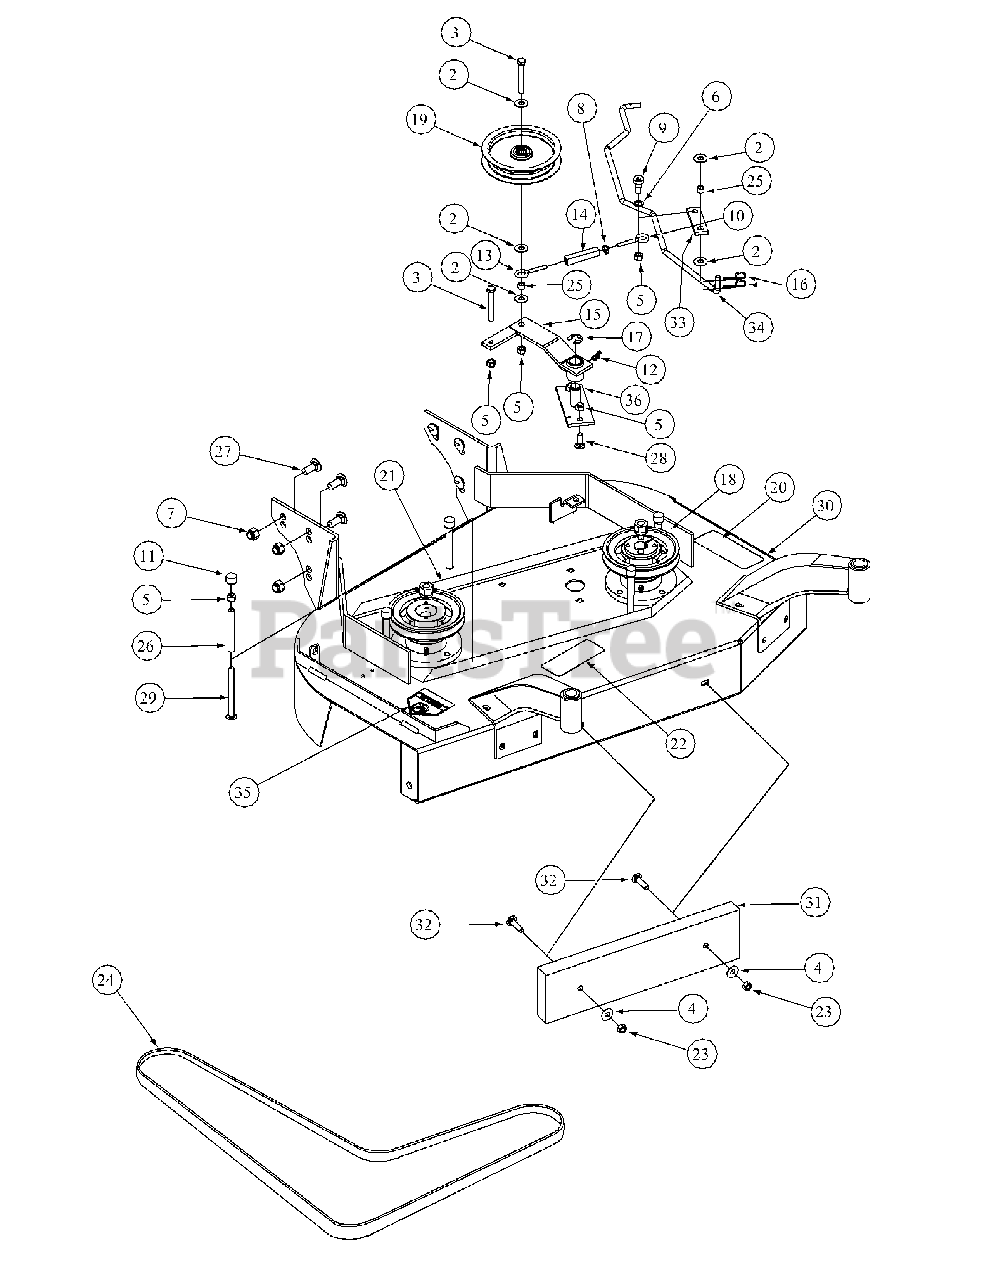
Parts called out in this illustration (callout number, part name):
2	Flat Washer, 3/8 Zinc
3	Hex Cap Screw, 3/8-16, 2.75
4	Flat Washer, 3/8 Zinc
5	Lock Nut, Nylon Insert, 3/8-16
6	Shim Washer
7	Lock Nut, Nylon Insert, 1/2-13
8	Hex Nut, 5/16-18
9	Shoulder Bolt
10	Eye Bolt, Right Hand
11	Cap, Black Vinyl
12	Grease Fitting, 1/4-28 45°.
13	Eye Bolt, Left Hand
14	Turnbuckle
15	Idler Arm
16	Hair Pin, 3/8"-1/2"
17	E-Ring, Retainer
18	Pulley Deck
19	Idler Deck Take-up
20	Decal Rotating Blade
21	Deck Stiffener
22	Decal, Warning Shield Missing
23	Lock Nut, 3/8-16
24	Belt Drive
25	Turnbuckle, Sleeve
26	Spacer, Belt Guide
27	Carriage Bolt, 1/2-13 x 1-1/4
28	Carriage Bolt, 3/8-16 x 2
29	Carriage Bolt, 3/8-16 x 4.5
30	Deck 36"
32	Carriage Bolt, 3/8-16 x 1-1/2
33	Clutch Link
34	Blade Deck Clutch Rod
35	Decal, Danger Hands and Feet
36	Idler Base
